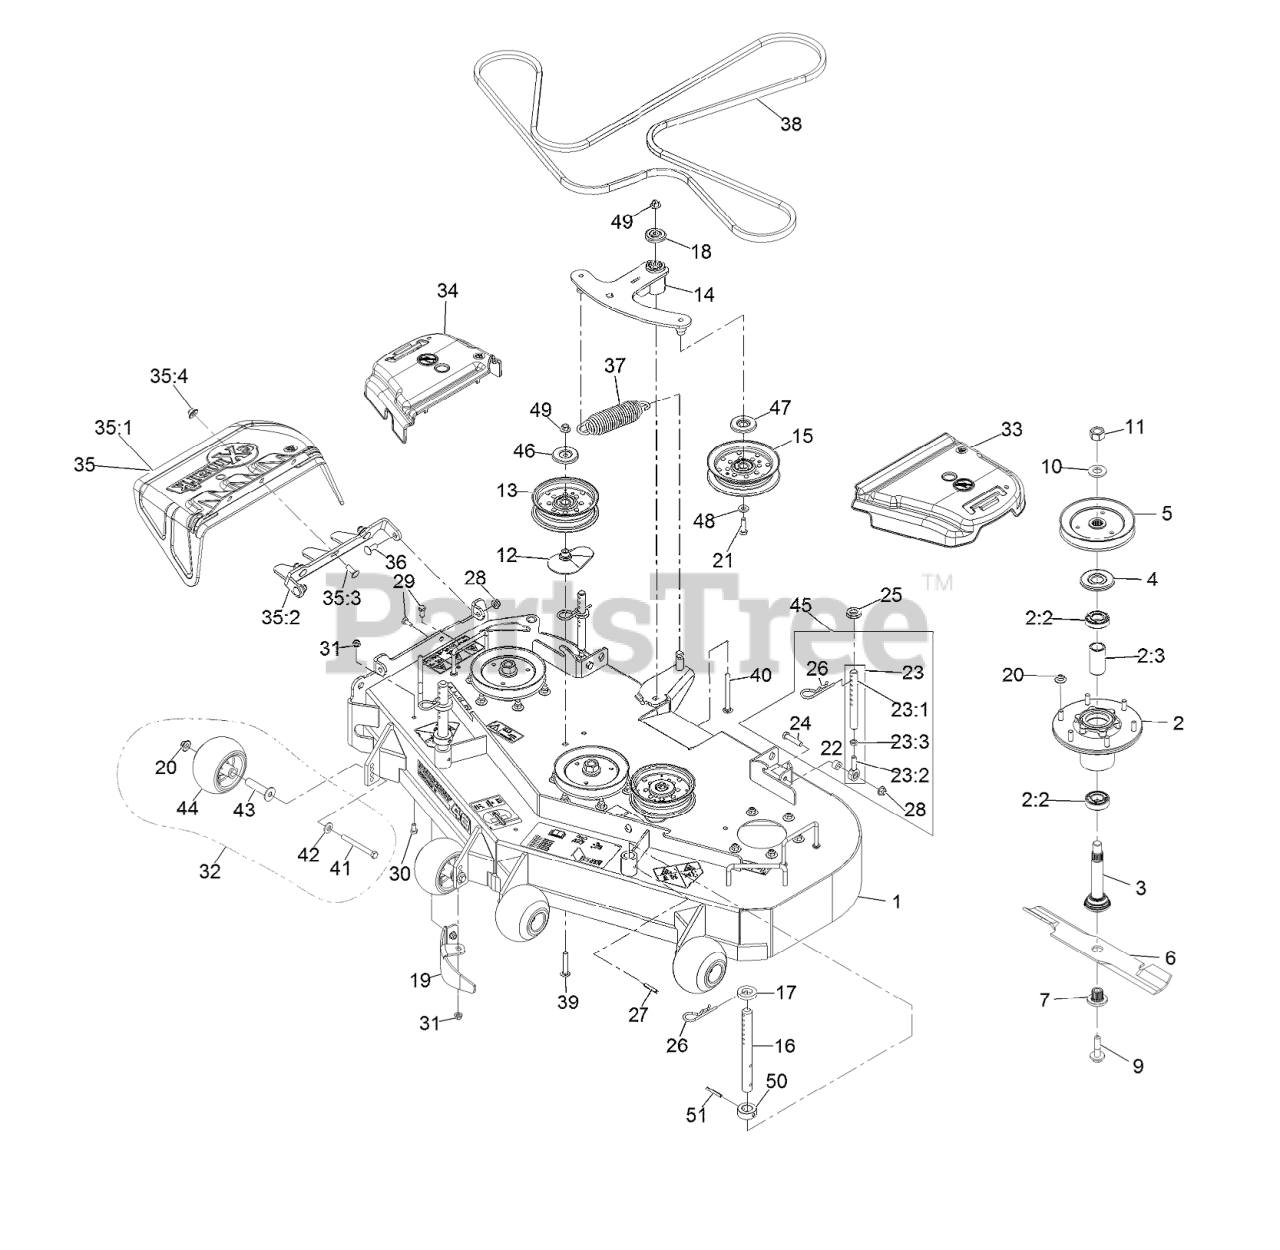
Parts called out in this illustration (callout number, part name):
1	ASM, DECK 48" W/DECALS
2	ASM-CUTTER HSG WITH BEARINGS
2:2	BEARING-BALL
2:3	SPACER-BEARING
3	ASM-SPINDLE AND SEAL
4	GUARD,BEARING TOP .989
5	SHEAVE,BLADE DRIVE 5.90
7	BUSHING,SPLINED
9	SCREW,SEMS 1/2-20 X 2.19
11	NUT-HEX
12	SPACER-PULLEY
13	IDLER-PULLEY, FLAT
14	ASM, DECK IDLER
16	ROD,DECK SUPPORT
17	SPACER-DECK SUPPORT
18	GUARD-TOP
19	BAFFLE, DOGLEG
20	Nut-Nyloc 3/8-16 Flg
21	SCREW-HFH
23:1	LINK,SUPPORT
23:2	BALLJOINT
23:3	NUT-HJ
24	SCREW-HH
26	PIN,HAIR COTTER
28	NUT-HF, NI
29	SCREW-HH
30	SCREW-HH
31	NUT-HF, NI
32	KIT, ANTI-SCALP ROLLER
33	COVER-BELT, LH
34	COVER-BELT, RH
35	ASM, DISCHARGE CHUTE
35:1	CHUTE,DISCHARGE
35:2	BRACKET, DISCHARGE CHUTE
35:3	SCREW-CARR
35:4	Nut-Nyloc 3/8-16 Flg
36	SCREW-CARR
37	SPRING-EXTENSION
38	BELT, DECK
39	BOLT-CARR, SHORT NECK
40	SCREW-CARR
41	SCREW-HH 3/8-16 X 3 3/4 GR 8
42	WASHER-BELLEVILLE
43	AXLE, ROLLER
44	ROLLER-SCALP, ANTI
45	KIT,SUPPORT LINK W/PIN
